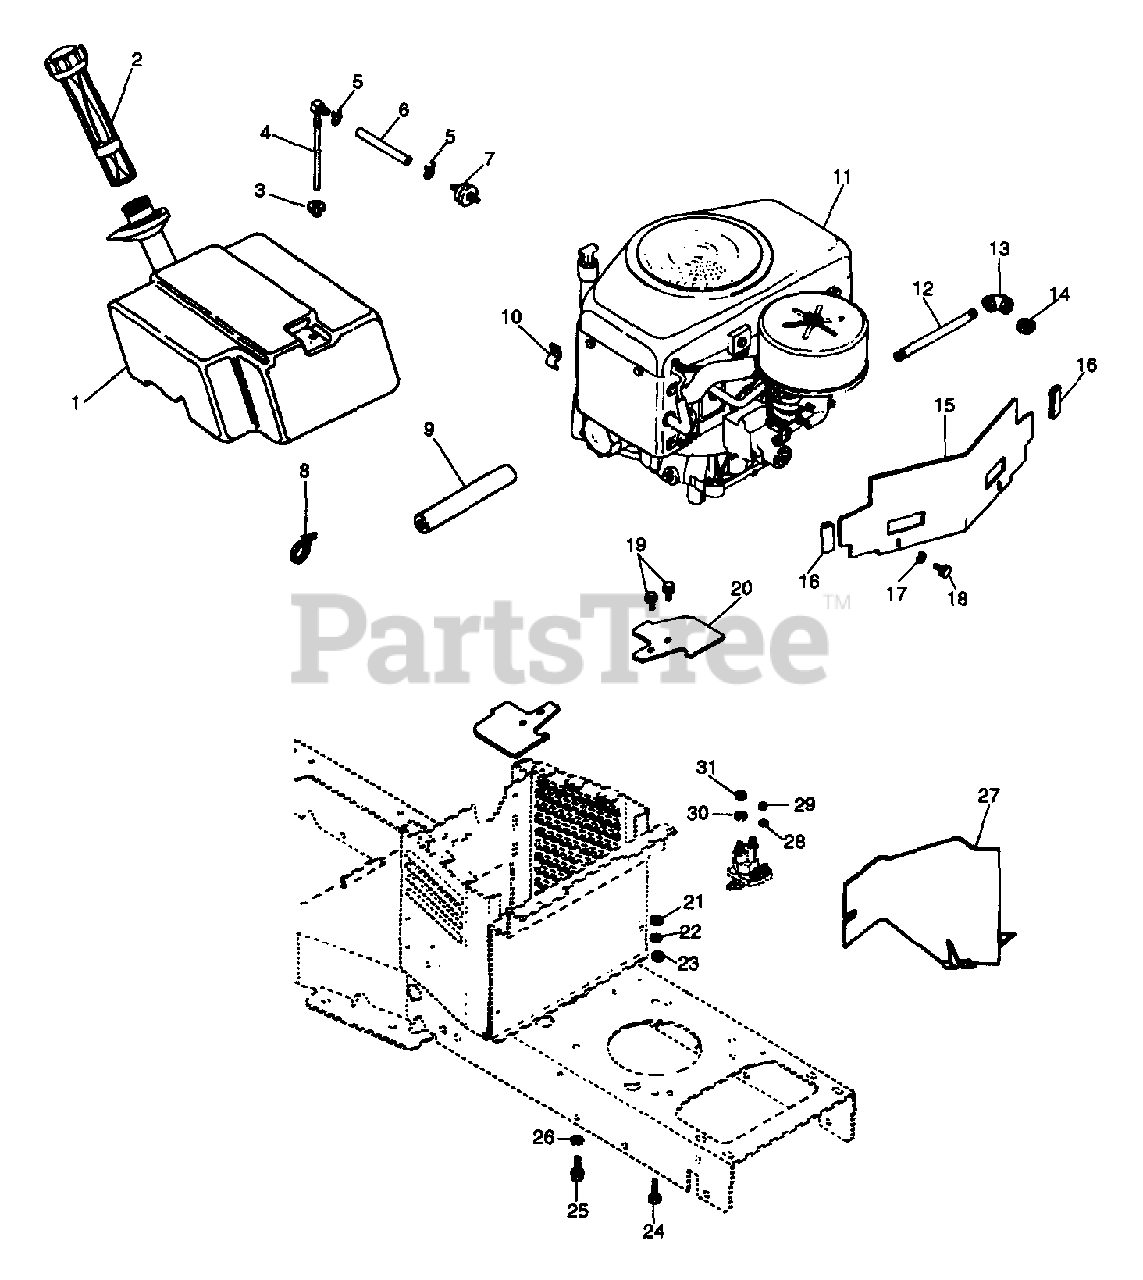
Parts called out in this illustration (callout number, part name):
1	FUEL TANK
2	FUEL GAUGE & CAP
3	BSHG-FLG .375 X 1.062 X .625 R
4	TANK FITTING
5	CLAMP-HOSE WIR.490/.510X.092#8
6	FUEL LINE 1/4 X 50.5"
6	FUEL LINE
6	FUEL LINE 14S
7	FUEL FILTER
8	CABLE TIE LG 5-1/2
9	TUBING - SPONGE
10	HOSE CLAMP
11	MV16S KOHL.VER.SHFT.ENG.#56514
11	MV18S KOHLER ENGINE - PS-58532
11	B&S 14 HP SINGLE
11	B&S 14HP TWIN
12	NIPPLE
12	OIL DRAIN PIPE
13	ELBOW
14	PIPE CAP
15	ENGINE BAFFLE
16	FOAM TAPE
17	WSHR-LK .250X.077 HVY PL
18	BLT-HEX .25-20X.38 PL GR2
19	SCR-TAP 10-24X.375 CRPH 1A
20	BAFFLE-SIDE
21	NUT-HEX .312-18
22	WSHR-LK .312X.097 PL HVY
23	WSHR-FL-STL .323X.625X.062 PL
24	BLT-HEX .31-18X1.50 PL GR5
25	SCR-TAP .375-16X1.0 HWH PL TR
26	SCR-TAP .375-16X1.0 HWH PL TR
26	WSHR-LK-EXT .375X.050
27	WSHR-LK-EXT .375X.050
27	SHIELD
28	WSHR-LK-EXT #10 ID X .022
29	NUT 10-32 PL
30	WSHR-LK-INT .313X.030 PL
31	NUT-JAM .312-24 PL
